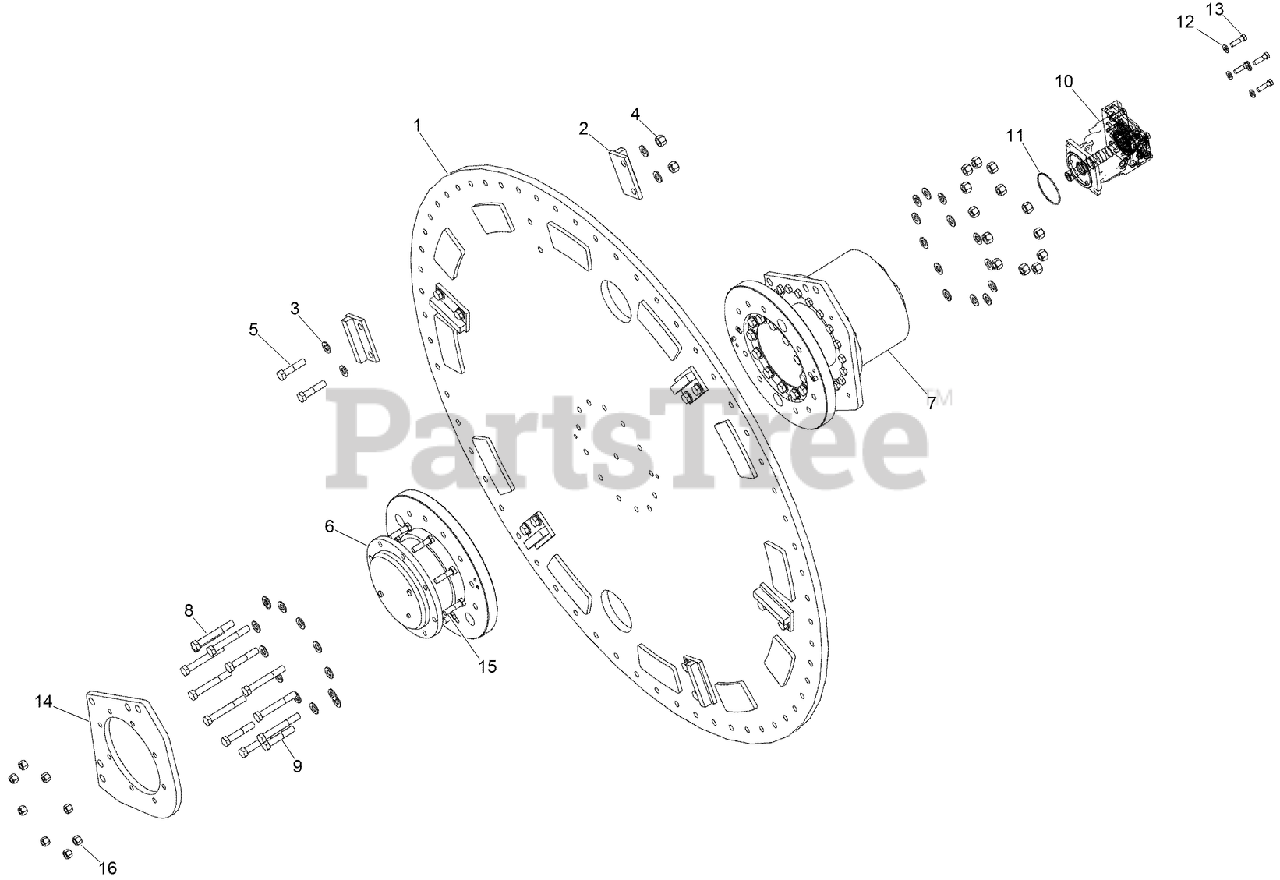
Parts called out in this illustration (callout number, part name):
1	WELDMENT - Wheel, 36 Cut
2	WELDMENT - Side Cutter
4	NUT-Prev Trq 3/4 GRC CAD Direct
5	BOLT - Hex Hd .75 x 3.25 GR8 ZND
6	ASSEMBLY - Model 9 Hub w/ Adaptor Plate
7	ASSEMBLY - Model 10 Gearbox w/Adaptor Plate
8	BOLT - Hex Hd, .750 x 5.50 GR8 ZND
10	PUMP - Sauer-Danfoss, 90 Series, 55cc
11	O-RING-Motor Seal
12	WASHER-FLAT
13	BOLT-Hex Hd 1/2 x 1-3/4 GR5 ZND
14	PLATE - Hub Mount
15	BOLT - 5/8 x 2-1/2
16	NUT-LOCK, HEX
